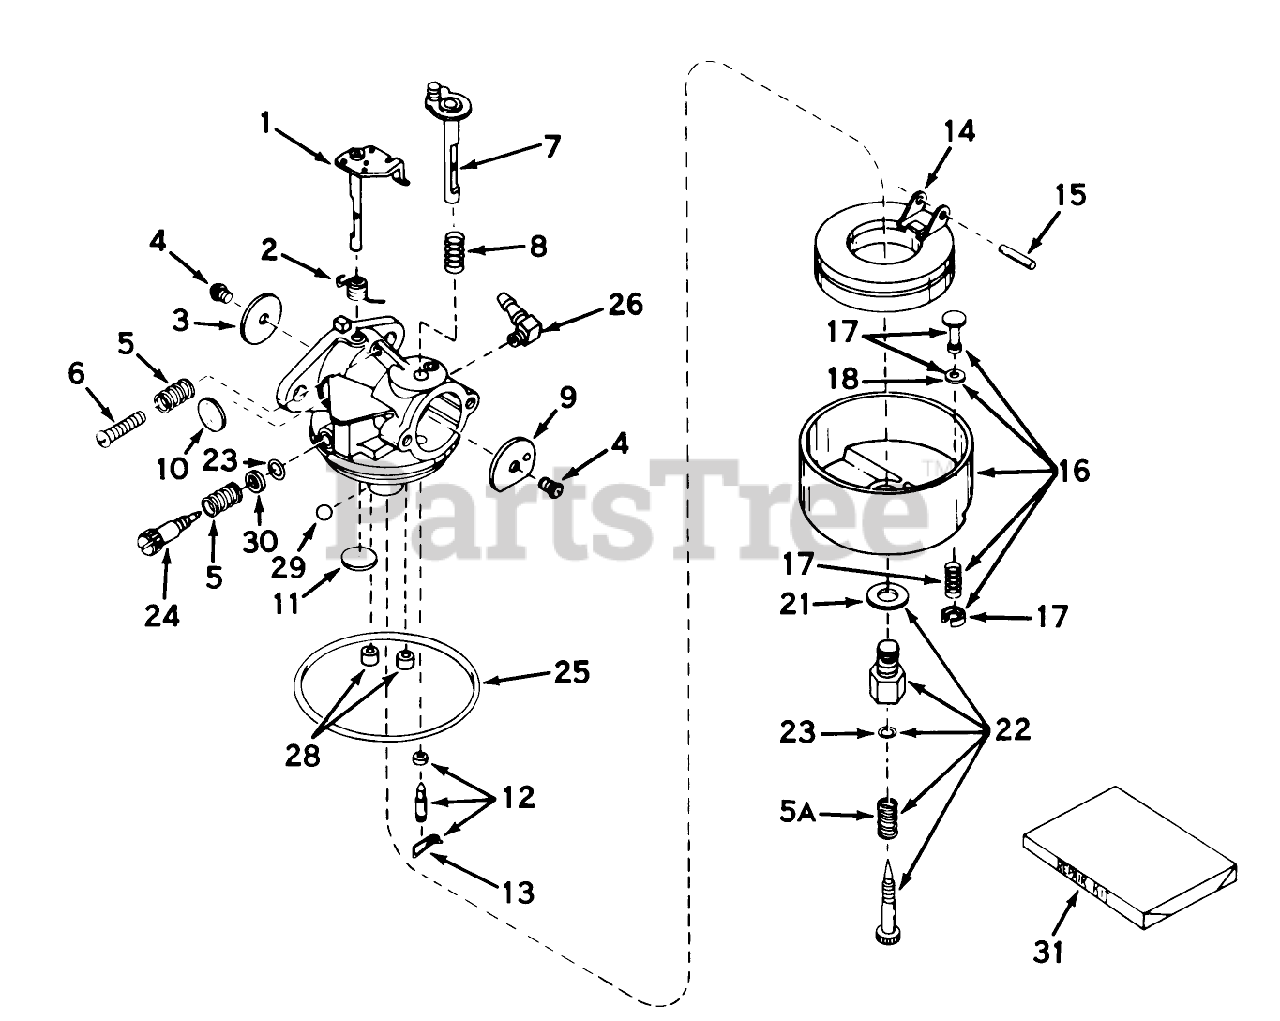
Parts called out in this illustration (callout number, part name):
16	Bowl Drain Assy., Float (Incl. No. 17)
17	Plunger Assy., Drain (Incl. Ref. 18)
18	Gasket-Plunger, Drain
21	Washer-Bowl Nut
22	Adjustment Screw Assy., Main (Incl. Nos. 5A, 21 23)
23	ORing
24	Screw, Idle Adj.
25	O Ring-Bowl, Float
26	Fitting Fuel Inlet
28	Plug, Cup
29	BalI, Steel
30	Washer
31	Repair Kit (Incl. items marked *)
